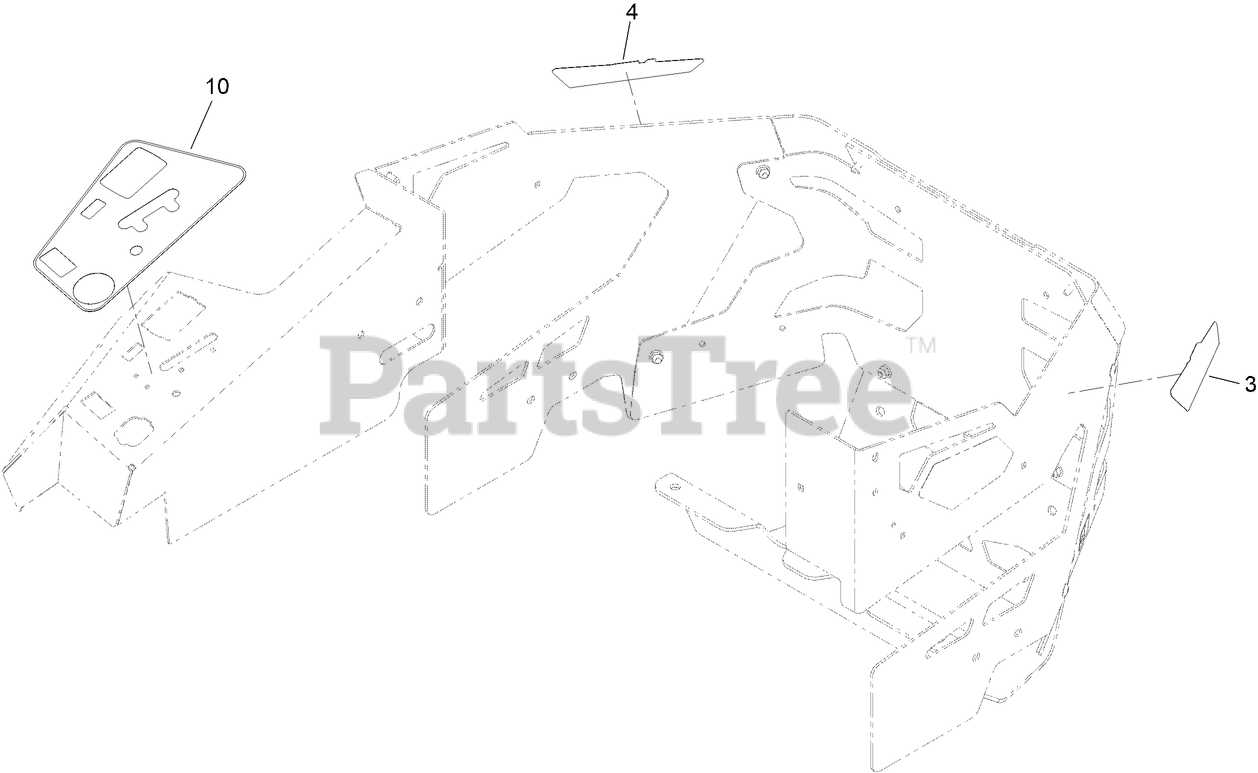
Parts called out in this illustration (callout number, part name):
3	DECAL - HD
4	DECAL - HD
10	DECAL-PANEL, CONTROL
